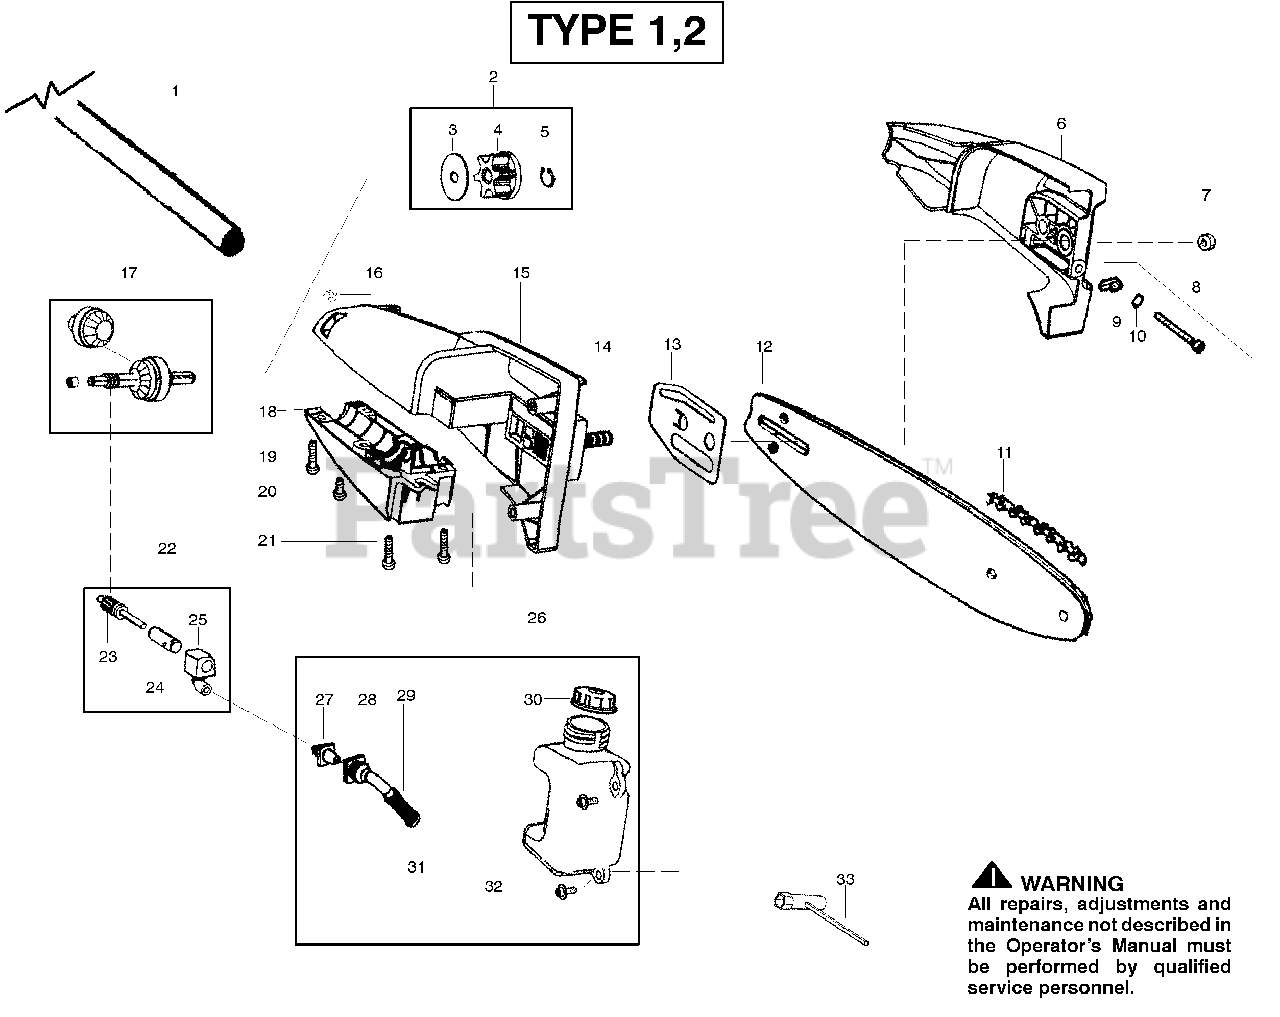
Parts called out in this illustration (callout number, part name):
1	Assy-Driveshaft
2	Kit-Sprocket Assy.
4	Sprocket
5	Retainer-Sprocket
6	Assy-Bar Clamp
7	Nut-Bar Mounting
8	Kit-Bar Adjust
9	Pin-Bar Adjust
10	Retainer-Bar Adjust
11	Accy.-Chain-8"
13	Plate-Bar pad
14	Bolt-Bar
15	Hsg.-Upper
17	Kit-Gear Assy
18	Hsg.-Lower
20	Screw-Align
22	Kit-Oil Assy
23	Assy-Gear Plunger
25	Block-Oil
26	Assy-Oil Tank
27	Fitting-Oil Line
28	Intake-Oil Line
29	Filter-Oil
30	Cap-Oil
31	Plug-Oil Filter
33	Wrench-Bar
